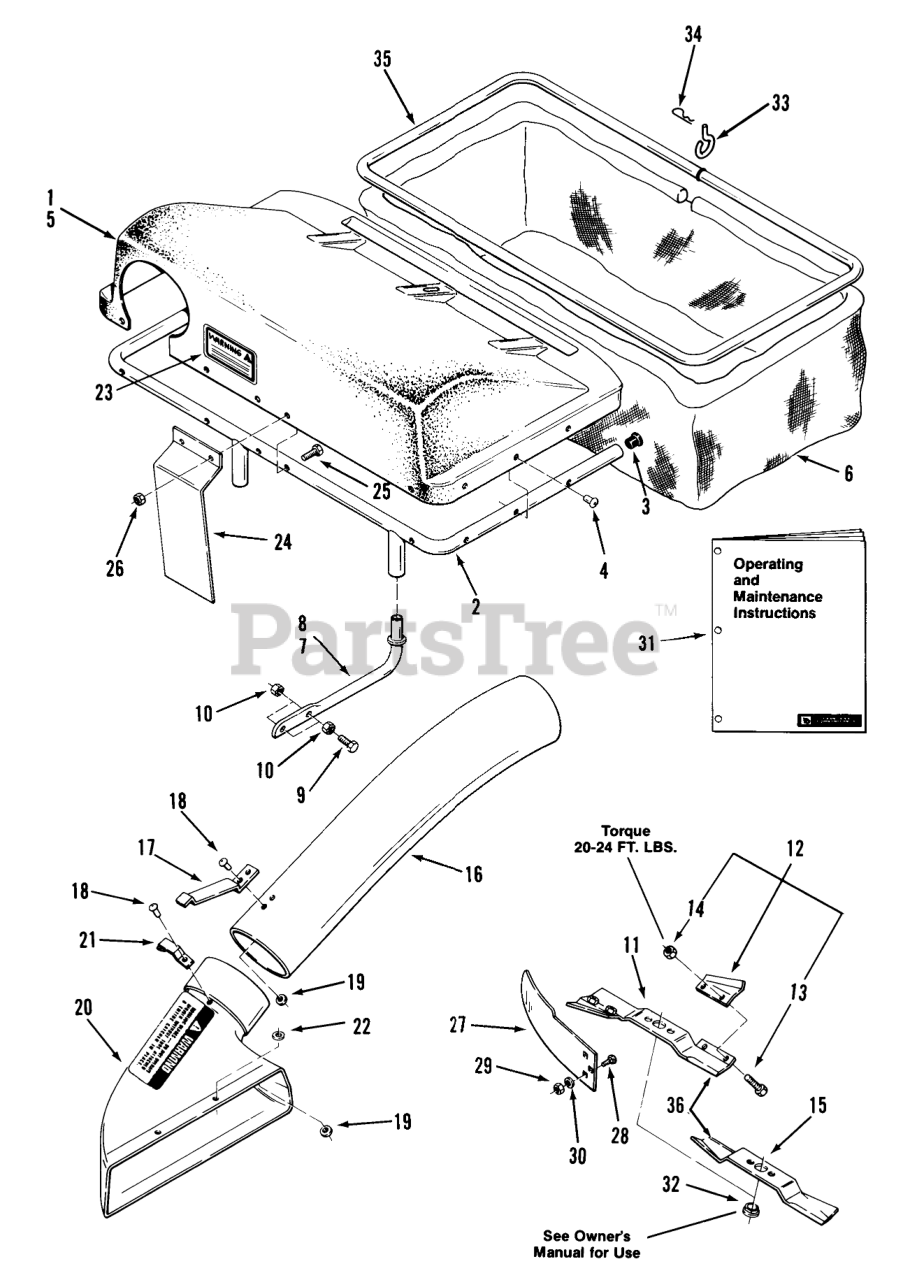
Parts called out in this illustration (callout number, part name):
13	BOLT 5/16-18X5/8
14	NUT-HEX
15	BLADE 16.50
21	BRACKET
27	BAFFLE-DEFLECTOR *B
31	Operating and Maintenance Instructions
32	SPACER BLADE
34	Hairpin Cotter
35	FRAME-BAG *B
